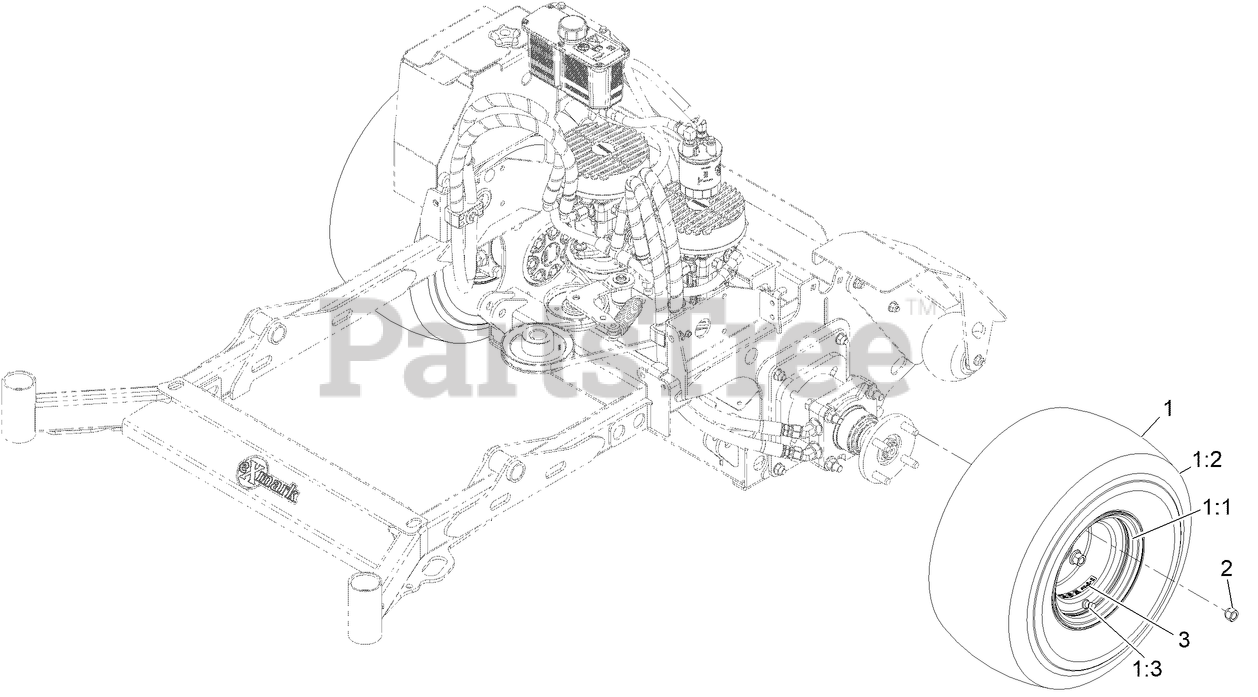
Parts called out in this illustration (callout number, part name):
1	WHEEL/TIRE ASM
1:3	VALVE
2	NUT-LUG
3	DECAL-TORQUE, WHEEL HUB LUG
